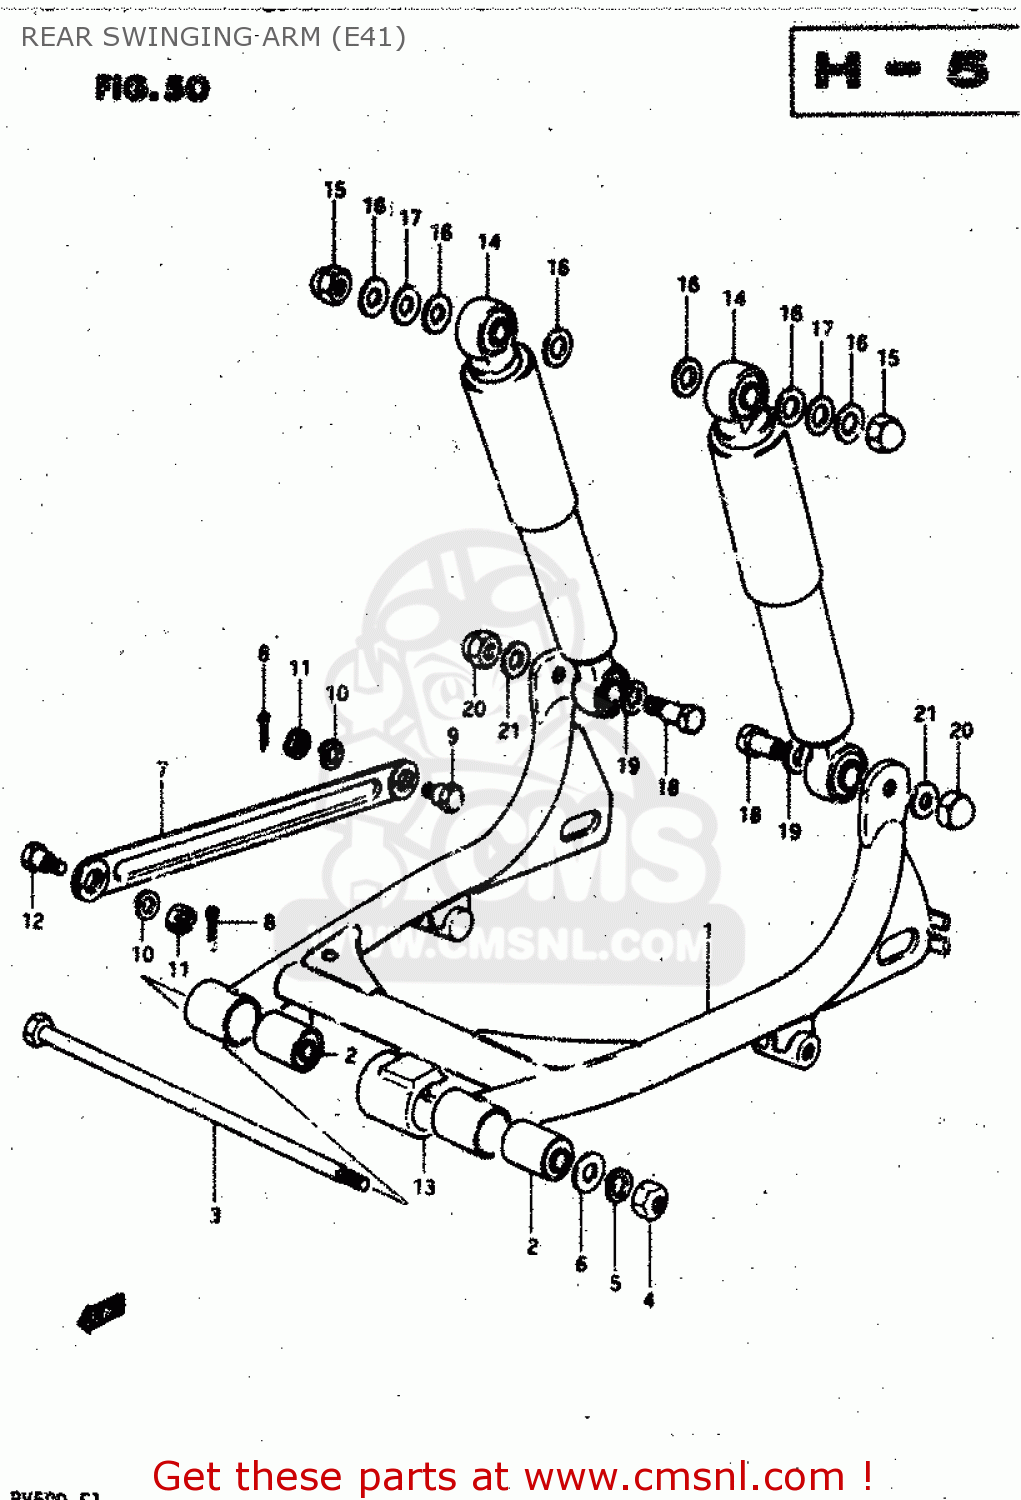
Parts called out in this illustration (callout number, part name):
1	SWINGING ARM SET, REAR
2	BUSHING(10X23X35)
3	SHAFT,REAR SWING ARM
4	NUT
5	LOCK WASHER
6	WASHER
7	LINK,RR BRAKE TORQUE
8	PIN
9	BOLT(8X26.5)
10	LOCK WASHER
11	NUT
12	BOLT(8X22.5)
13	BUFFER,CHAIN TOUCH DEFENSE
14	SHOCK ABSORBER ASSY
15	NUT, LOWER LH
16	WASHER
17	WASHER(10.5X24X3.2)
18	BOLT
19	WASHER
20	NUT, LOWER LH
21	WASHER
